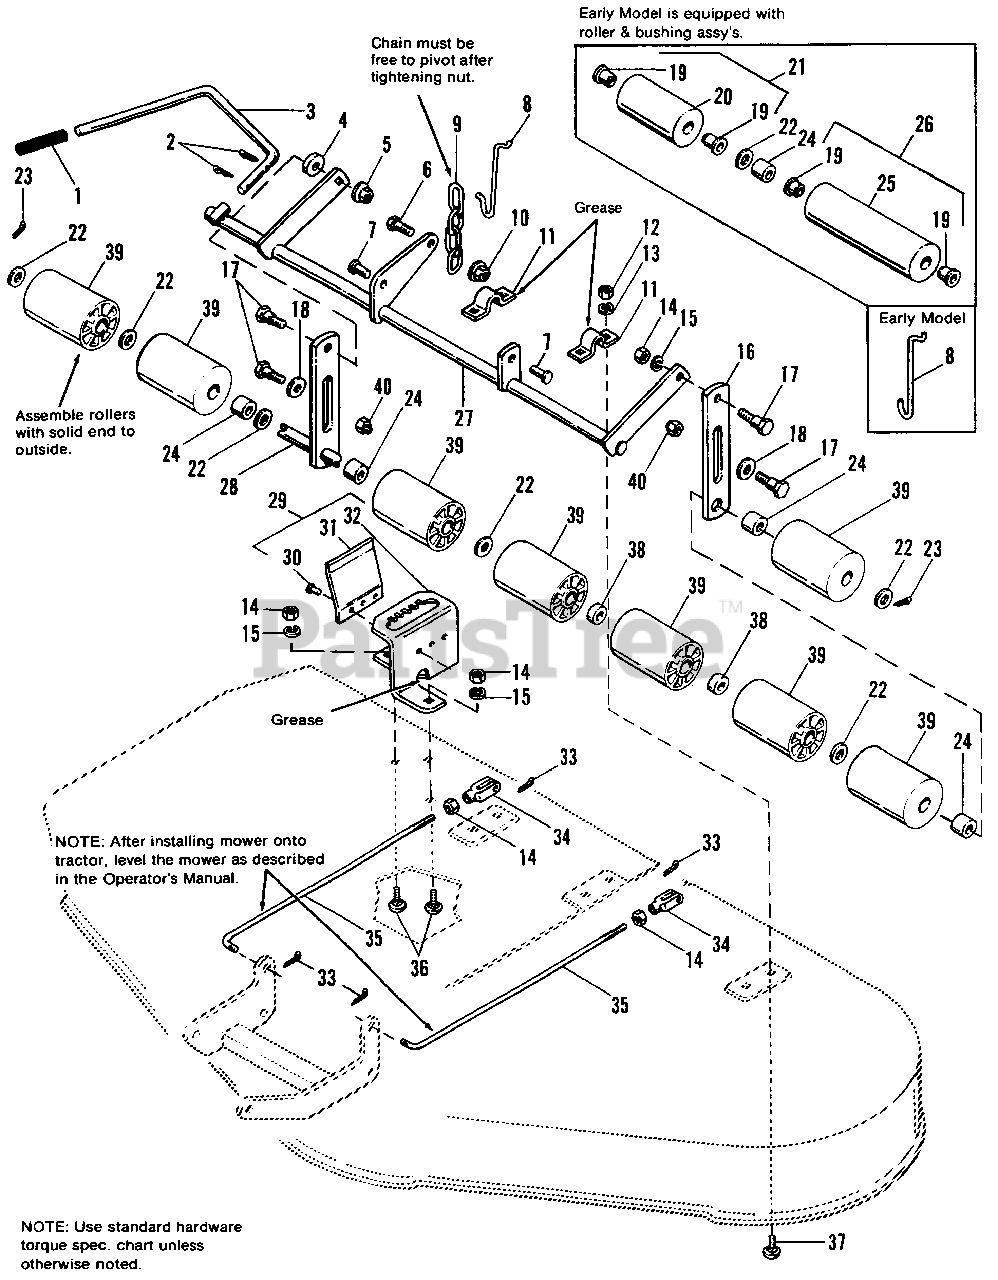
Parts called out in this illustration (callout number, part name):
2	PIN. Cotter, 1/8 x 1
3	LEVER, Control
4	WASHER, Plain, 13/32
5	LOCKNUT, Hex, Flange, Whiz, 3/8-16
6	CAPSCREW, Hex, 5/16-18 x 1
7	PIN, Clevis
8	***ROD, Lift (Later Models)
8	ROD, Lift (Early Models)
9	CHAIN, Lift
10	LOCKNUT, Flange, 5/16-18
11	STRAP
12	NUT, Hex, 5/16-18
13	LOCKWASHER, 5/16
14	NUT, Hex, 3/8-16
15	LOCKWASHER, 3/8
16	BAR, Roller
17	BOLT, Shoulder, 3/8-16 X 1.34
18	WASHER, Plain, 7/16
21	ROLLER ASSY., Small (Includes Bushings)
22	WASHER, 25/32 x 1-1/4 (Qty. 11 used on mowers with roller and bushing assy.'s as in Ref. Nos. 21 & 26)
23	PIN, Cotter, 3/16 x 1
24	SPACER, .66 ID
25	ROLLER, Large (Not serviced w/o bushings)
26	*ROLLER ASSY., Large (Includes Bushings)
27	ARM ASSY., Mower
28	**SHAFT ASSY., Roller
28	*SHAFT ASSY., Roller
29	**QUADRANT ASSY.
33	PIN, Cotter, 3/32 x 3/4
34	CLEVIS, Adj.
36	BOLT, Carriage, 3/8-16 x 3/4
37	BOLT, Carriage, 5/16-18 x 3/4
40	NUT, Esna Locknut. 3/8-16
